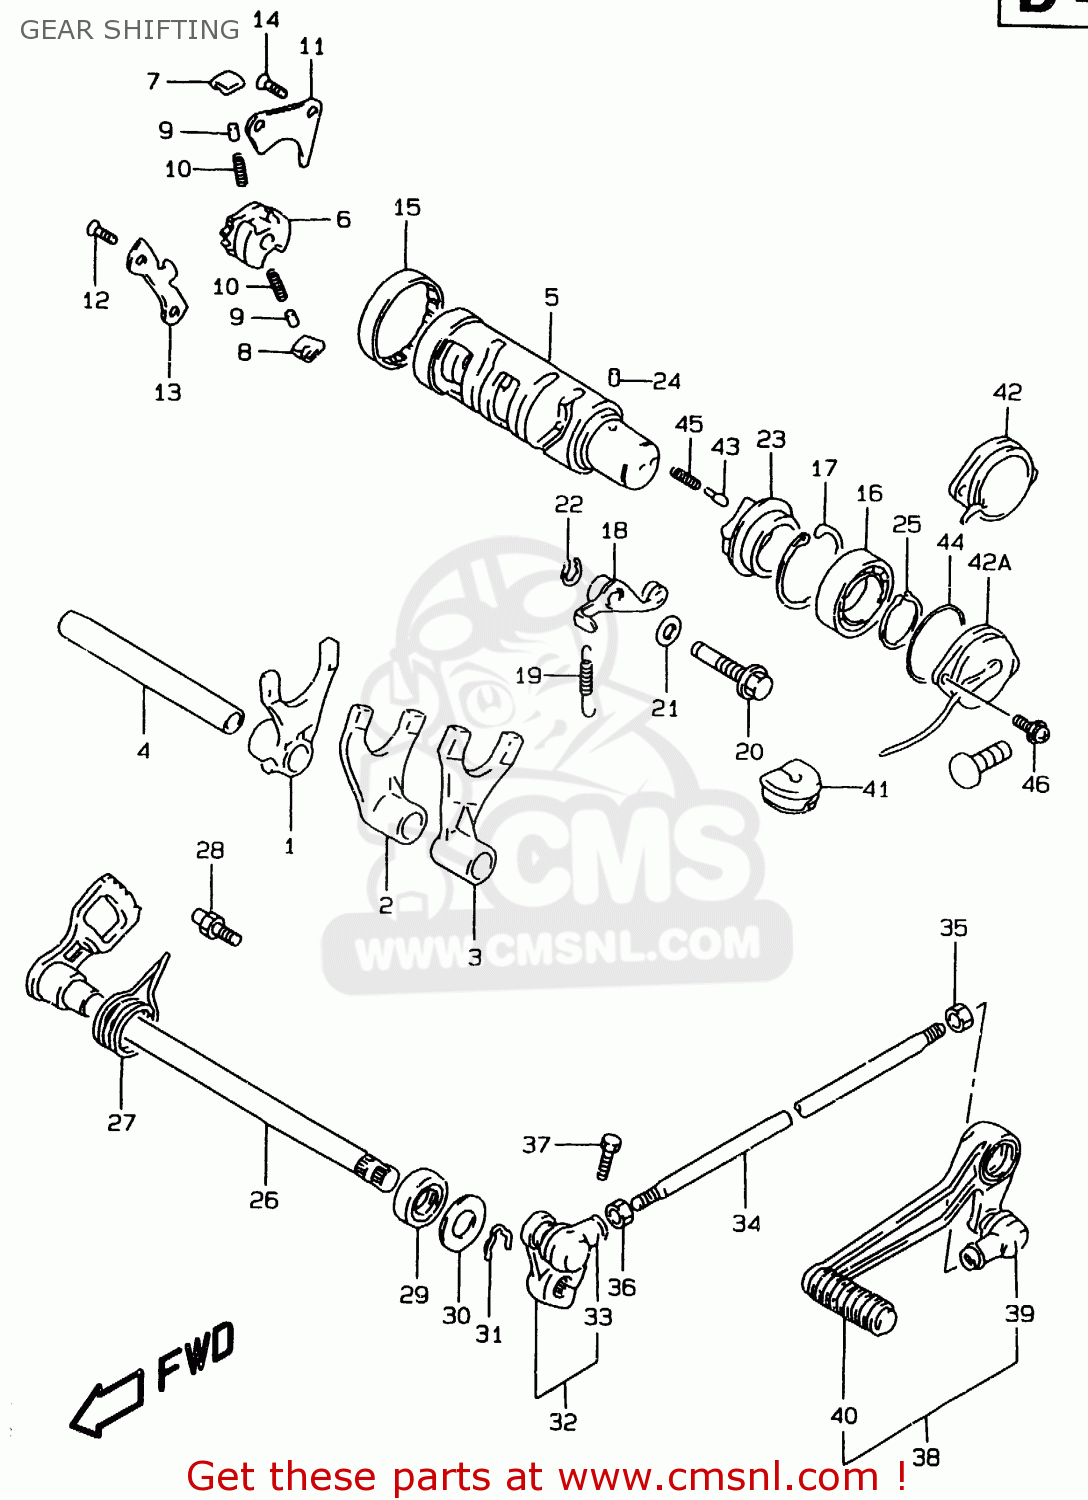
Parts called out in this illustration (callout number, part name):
1	FORK,GEAR SHIFT NO.1
2	FORK,GEAR SHIFT NO.2
3	FORK,GEAR SHIFT NO.3
4	SHAFT,GEAR SHIFT FORK(L:128)
5	CAM,GEAR SHIFT
6	GEAR,GEAR SHIFT CAM DRIVEN
7	PAWL,GEAR SHIFT NO.1
8	PAWL,GEAR SHIFT NO.2
9	PIN(5X8)
10	SPRING
11	LIFTER,GEAR SHIFT PAWL
12	SCREW
13	GUIDE,GEAR SHIFT CAM
14	SCREW
15	BEARING(43X49X12)
16	BEARING
17	CIRCLIP
18	STOPPER,GEAR SHIFT CAM
19	SPRING
20	SHAFT,GEAR SHIFT CAM STOPPER
21	GASKET(10X14X3.6) (NAS)
22	CIRCLIP
23	PLATE,STOPPER
24	PIN
25	CIRCLIP
26	SHAFT,GEAR SHIFT
27	SPRING
28	STOPPER,GEAR SHIFT CAM
29	OIL SEAL
30	WASHER (12.5X27X1.6)
31	CIRCLIP,12 MM
32	ARM,GEAR SHIFT LINK
33	COVER,DUST
34	ROD,GEAR SHIFT LINK
35	NUT
36	NUT
37	BOLT
38	LEVER ASSY,GEAR SHIFT
39	COVER,DUST
40	RUBBER,GEAR SHIFT PEDAL
41	GROMMET,LEADWIRE
42	BASE ASSY,GEAR SHIFT TERMINAL
42A	TERMINAL BASE ASSY,NEUTRAL
43	PIN(5X15.5)
44	O RING(D:2.4,ID:35.5)
45	SPRING
46	SCREW
